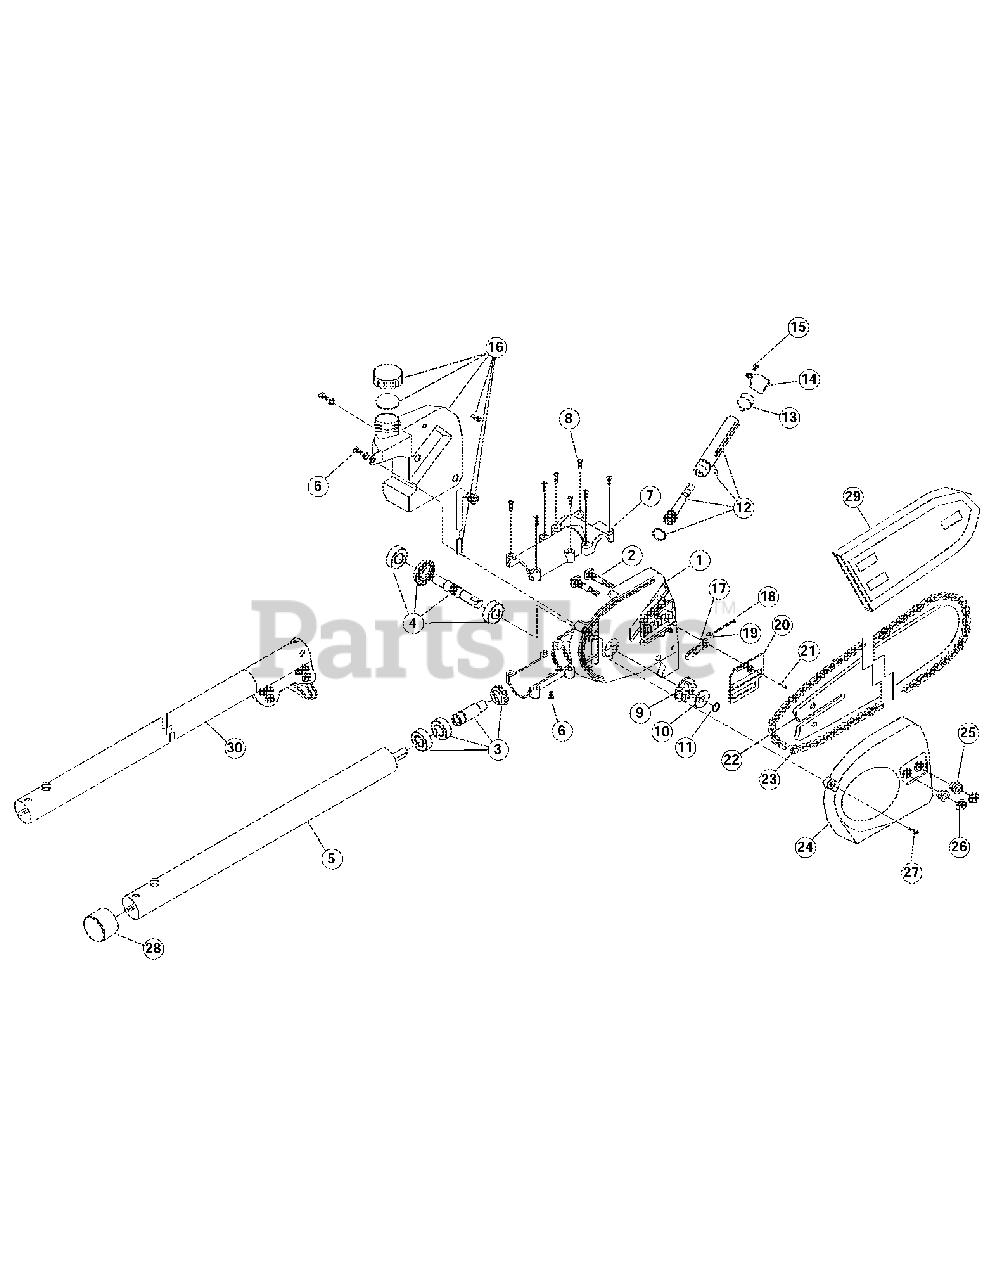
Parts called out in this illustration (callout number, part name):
3	Shaft Assembly
4	Spindle Assembly
5	Connection Stick Assembly
7	Case Cover
11	C Ring
12	Oil Pump Assembly
13	Rubber Cork
14	Fixed Plate
16	Oiler Assembly
17	Anti-Spillage Pad
18	Regulation Screw
19	Regulation Cap
20	Adjustable Plate
25	Fixed Ring
26	Nut
28	Covering
30	Inner Pipe Assembly
